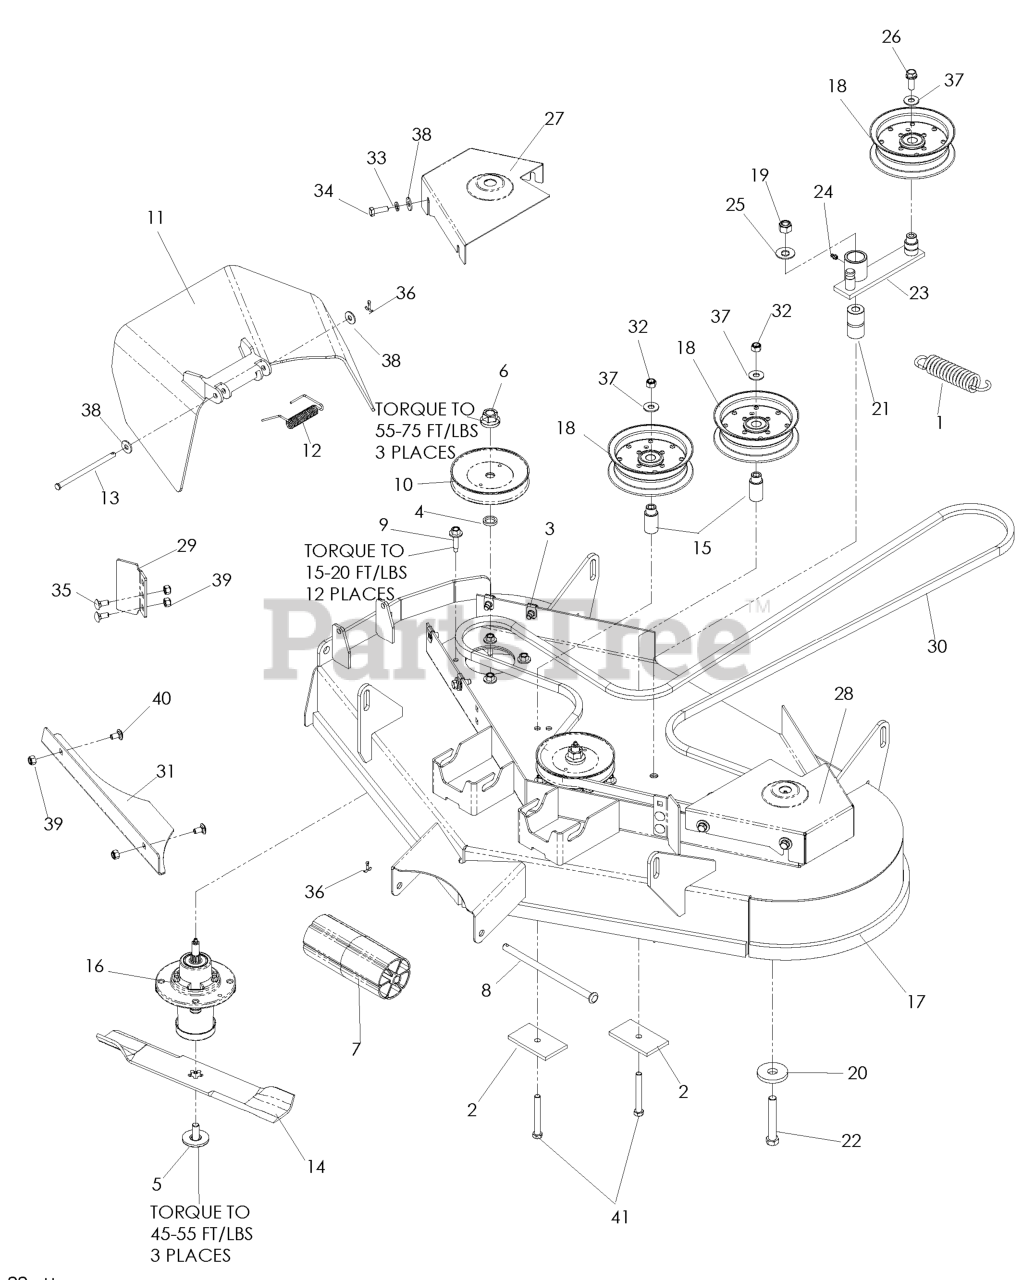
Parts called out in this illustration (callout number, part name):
2	SUPPORT PLATE
3	U-CLIP 5/16-18 NUT RETAINER
4	WASHER-SPACER
5	BLADE BOLT ASSY-7/16" TB REPL
6	LOCKNUT - 9/16
7	NOSE ROLLER 48"
8	NOSE ROLLER ROD
9	WASHER HEAD SCREW
10	PULLEY MANDREL
11	DISCHARGE CHUTE 42"
12	SPRING - TORSION
13	PIN-CLEVIS 5/16 DIA X 5.19 ZD
14	BLADE, 14 5/8"
15	IDLER BUSHING
16	MANDREL.DECK.ASSEMBLY
17	DECK W/DECALS 42"
18	PULLEY, IDLER
19	NUT 1/2-13 HEX NYLOC ZD
20	WASHER, SUPPORT
21	PIVOT BUSHING
22	HCS 1/2C X 3 1/4
24	ZERK
25	WASHER 1/2 FLAT
26	4CS 3/8C X 1 SERRATED HEAD
27	BELT SHIELD, RIGHT 42, ORG
28	BELT SHIELD, LEFT 42, ORG
30	BELT, DECK 42"
31	CONFINEMENT.PLATE.42".BLACK
32	NUT 3/8-16 NYLOC
33	WASHER.LOCK.HVY.HLCL.SPR.5/16
34	HCS 5/16C X 1
35	BOLT 5/16C X 3/4" CARRIAGE
36	RP_COTTER PIN 1/8 X 3/4
37	WASHER 3/8 FLAT
38	WASHER 5/16 FLAT
39	NUT 5/16 NYLOC
40	CARRIAGE BOLT 5/16C X 5/8"
41	HCS 3/8C X 3
